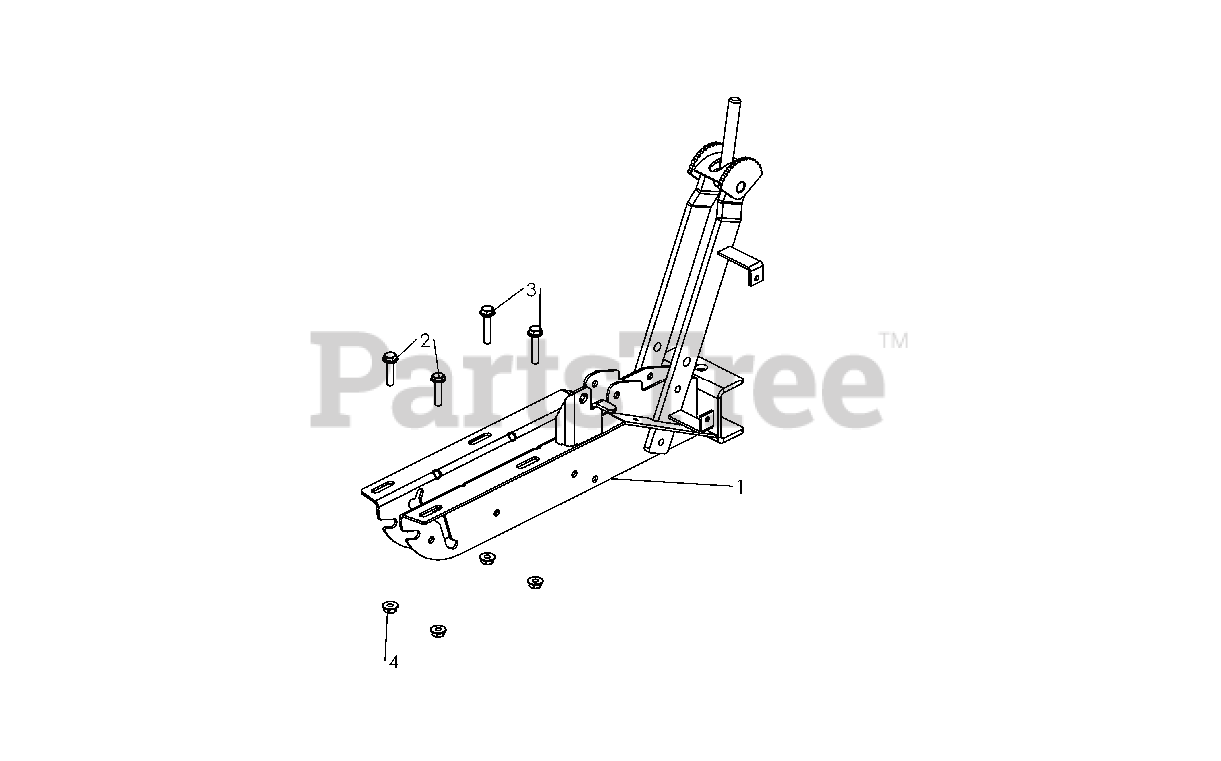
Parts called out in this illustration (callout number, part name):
2	SCREW
3	SCREW
4	NUT
